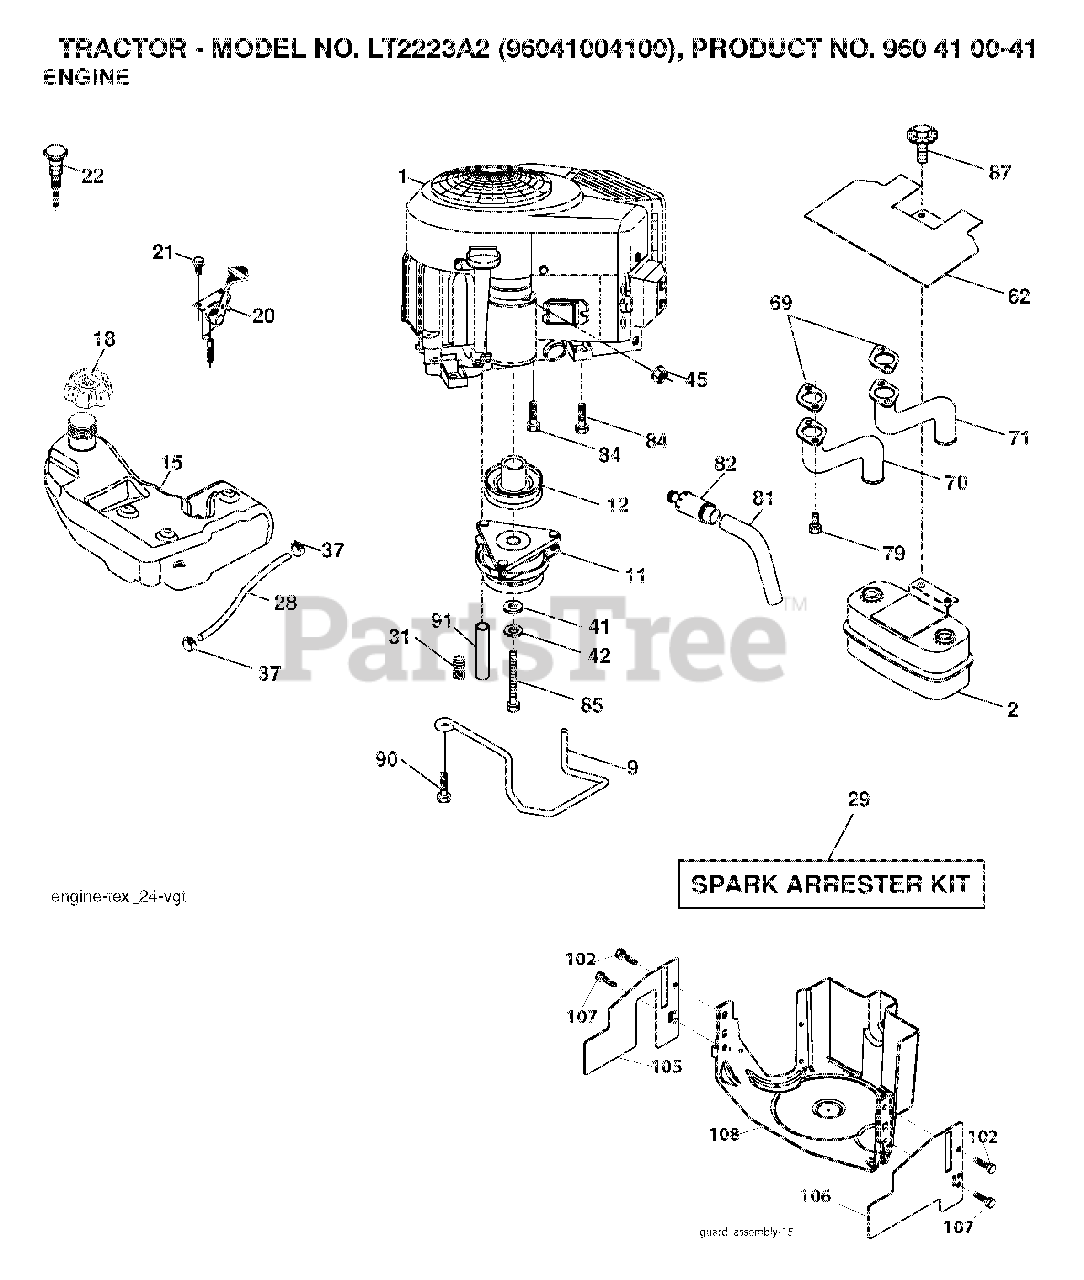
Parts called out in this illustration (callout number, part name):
2	MUFFLER.TWIN.CYL.LOW.TONE
9	KEEPER.BELT.ENGINE.4.2
11	CLUTCH ELECTRIC
12	PULLEY ENGINE
15	TANK.FUEL.4GAL
18	CAP.ASM.FUEL.TANK.3"BL
20	THROTTLE CABLE
21	SCREW
22	CONTROL CHOKE
29	ARRESTER SPARK (OPTIONAL)
31	PUSH CLIP
37	HOSE CLAMP
42	LOCKWASHER
45	NUT
62	RP SHIELD HEAT MUFFLER
69	GASKET.MUFFLER
70	TUBE MANIFOLD LH
71	EXHAUST TUBE RH
79	SCREW.SOCKET.HEAD.5/16-18
81	TUBE, DRAIN OIL ASM.
82	PLUG DRAIN OIL EASY
84	SCREW.3/8-16
85	BOLT HEX 7/16-20 X 3.75 GR. 5
87	BOLT.5/16-18UNCX1.W/SEMS.BLK
90	SCREW 3/8-16X1
91	BUSHING.1.375OD
102	SCREW
105	SHIELD SIDE
106	SHIELD SIDE
107	SCREW.1/4-20X5/8
